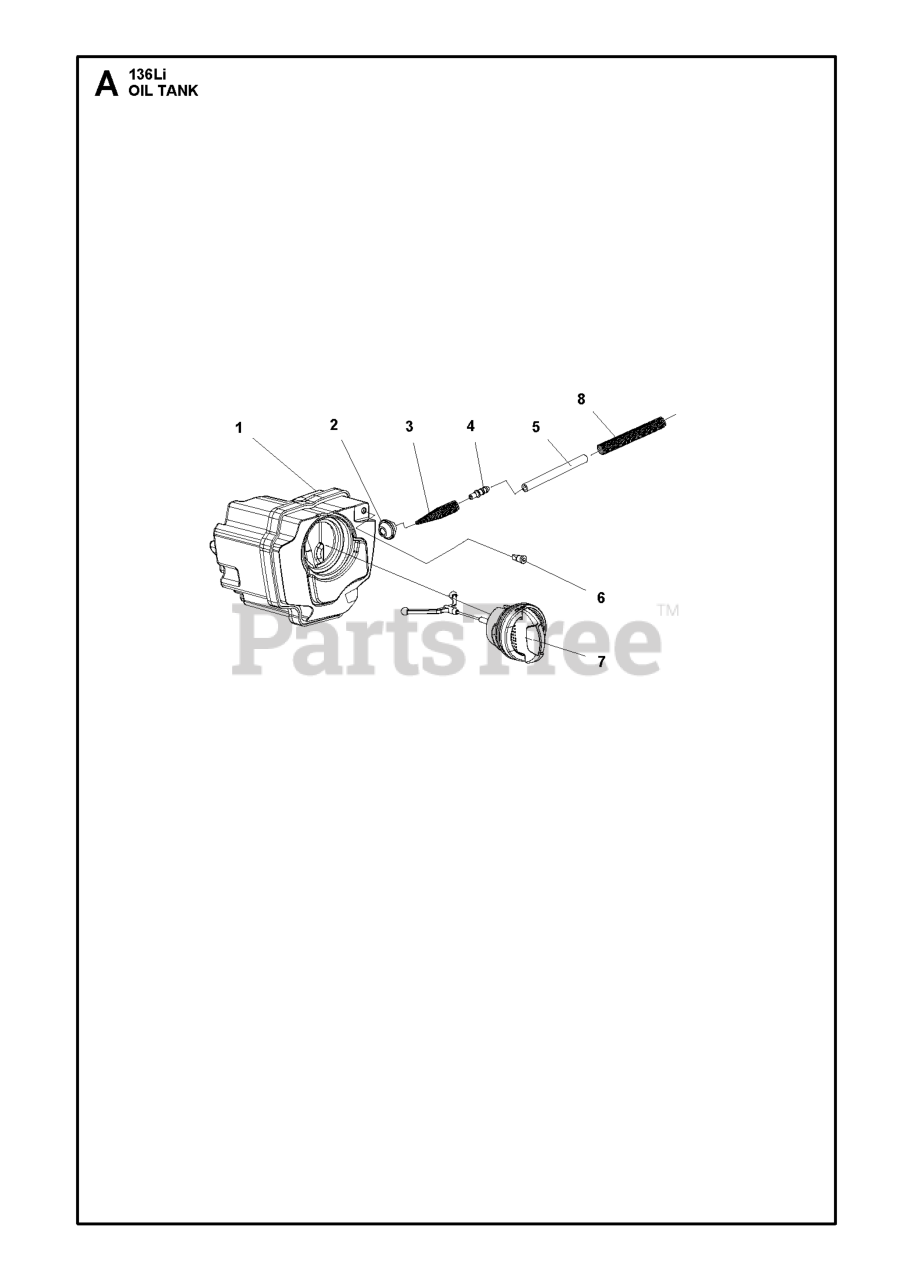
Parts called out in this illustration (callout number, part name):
2	PLUG RUBBER
3	SPRING SPRING FILTER 36V
5	OIL HOSE WHITE AND TRANSPAREN
6	VALVE, FUEL INLET
7	TANK CAP ASSY
8	SPRING PIN SPRING, OIL HOSE S
